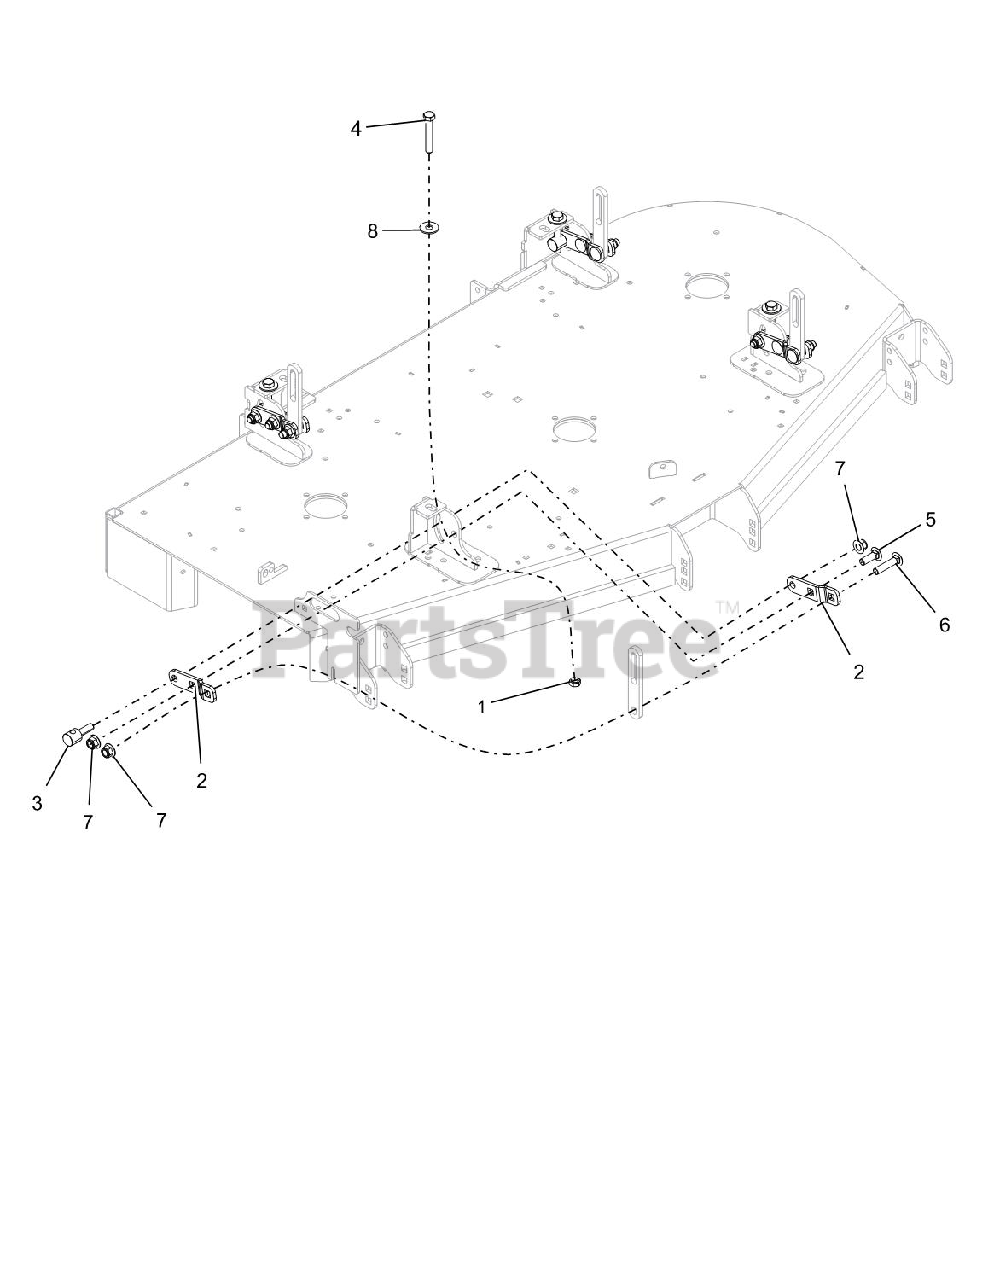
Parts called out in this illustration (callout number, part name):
1	NUT-JAM .50-13 YWZC
2	DECK LEVELING BRACKET - BLACK
3	TRUNNION, .50-13
4	BLT,HEX .50-13X3.00 GR5 FTH YZ
5	BLT-RDHDSQNK .50-13X1.50 G5YZ
6	BLT-RDHDSQNK .50-13X2.25 G5YZ
7	NUT-LK-NYL-FLG .50-13 YWZC
8	WSHR-FL-STL.563X1.38X.109YWZC
